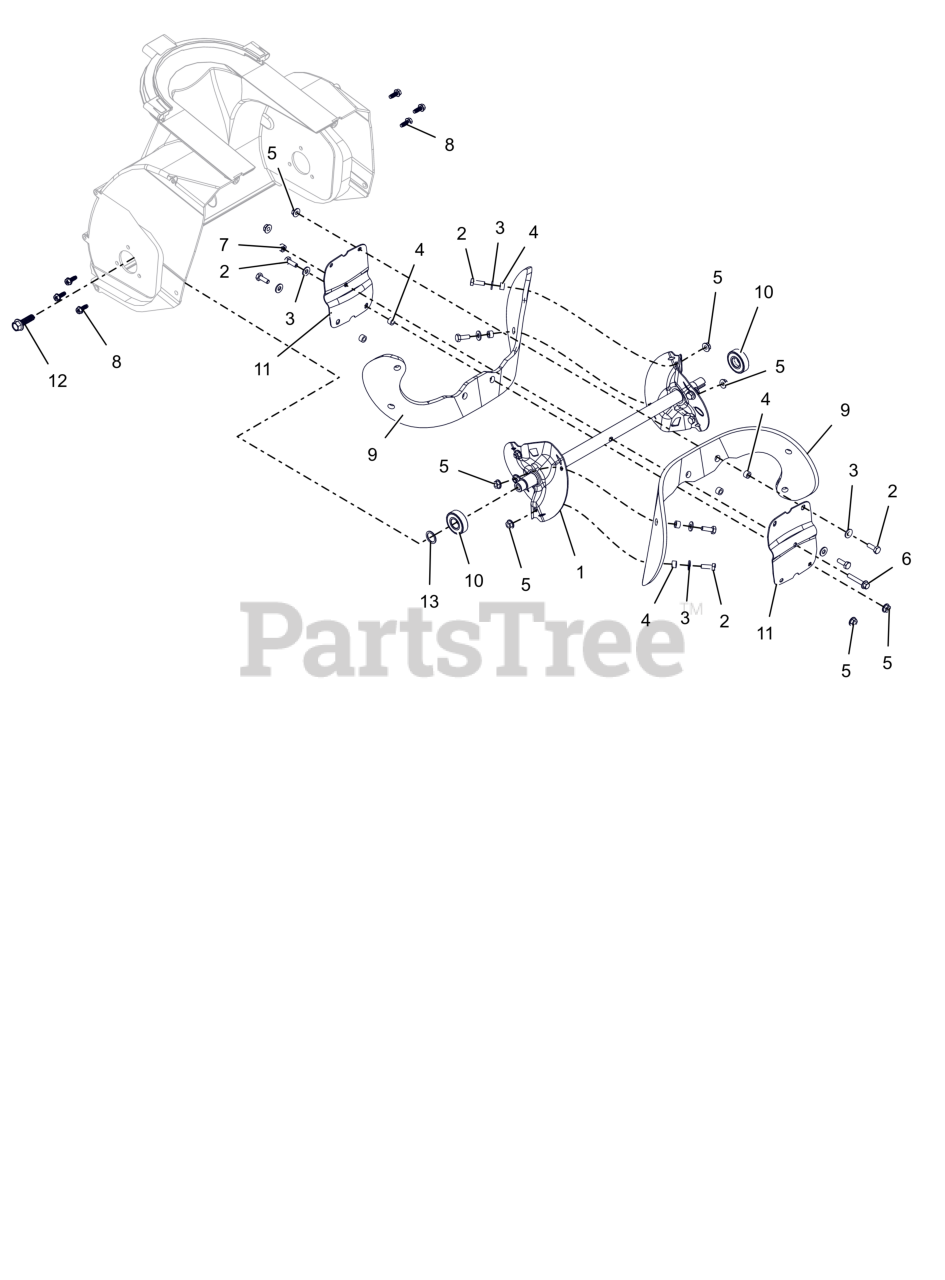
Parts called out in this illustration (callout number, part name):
1	WLDMT, ROTOR
2	BLT, HEX .25-20X.75 G5 ZCC
3	WSHR,FLT .281X.625X.065 ZCC
4	BUSHING, .26 ID X .44 OD X .26
5	NUT-LK-CTR-FLG .25-20 ZC120
6	BLT, HEX - FLG .25-20X1.5 BLACK
7	NUT, NYLON .250 - 20 (BLACK)
8	1/4-20 X 5/8 TAPTITE
9	KIT, PADDLE REPLACEMENT 18IN
10	BRG-BALL .669X1.575X.47(6203Y)
11	PLATE, CENTER AUGER
12	BLT, HEX -FLG .375-16X1.25 BLACK
13	WSHR, THRUST
